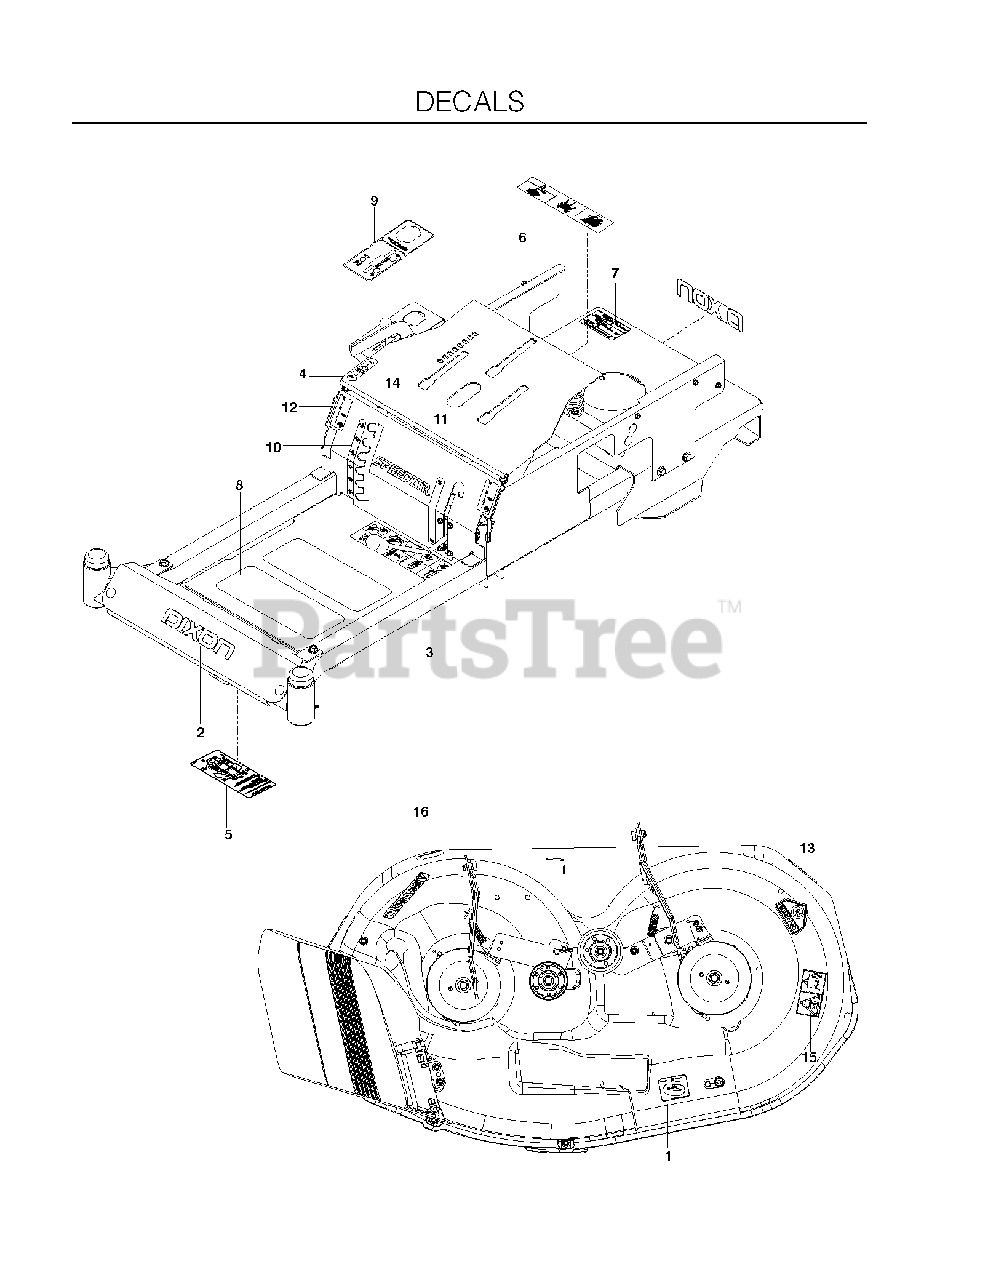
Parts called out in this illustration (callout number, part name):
1	DECAL, BELT ROUTING
3	DECAL, SAFETY WARNING
4	DECAL, PARK BRAKE
5	DECAL, SERVICE
6	DECAL, BATTERY
7	DECAL, DO NOT MOUNT
8	ANTI-SKID PAD
9	DECAL, CONTROL PANEL
10	DECAL, DECK HEIGHT
11	DECAL, BLADE ENGAGEMENT
12	DECAL, MOTION CONTROL
13	DECAL, CPSC
14	DECAL, SPEEDZTR 6.5"
15	DECAL, EURO SEVERING
